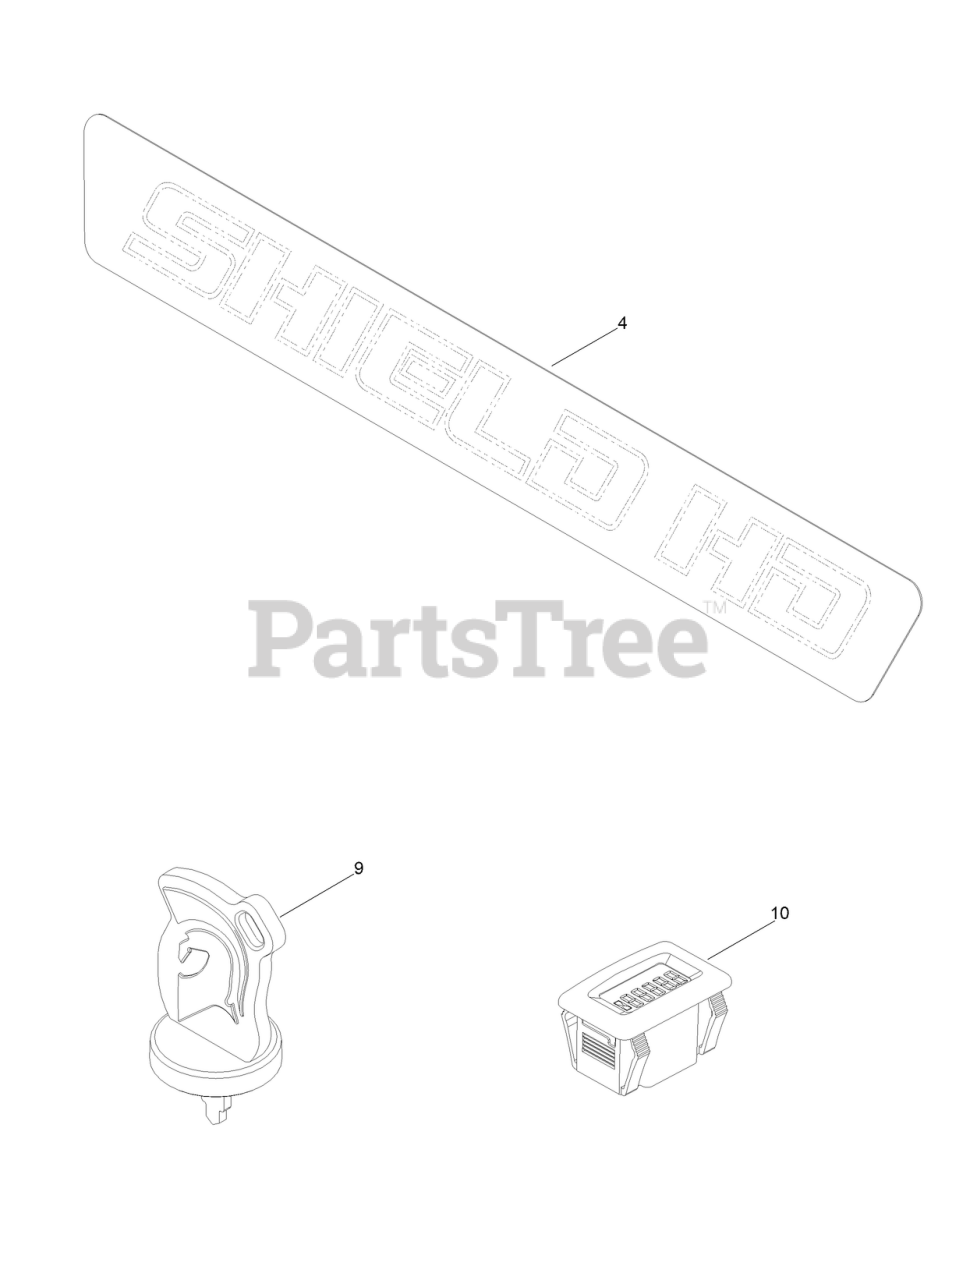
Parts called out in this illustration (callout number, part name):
4	DECAL - SHIELD-HD, FRONT
9	KEY-IGNITION
10	HOUR METER
